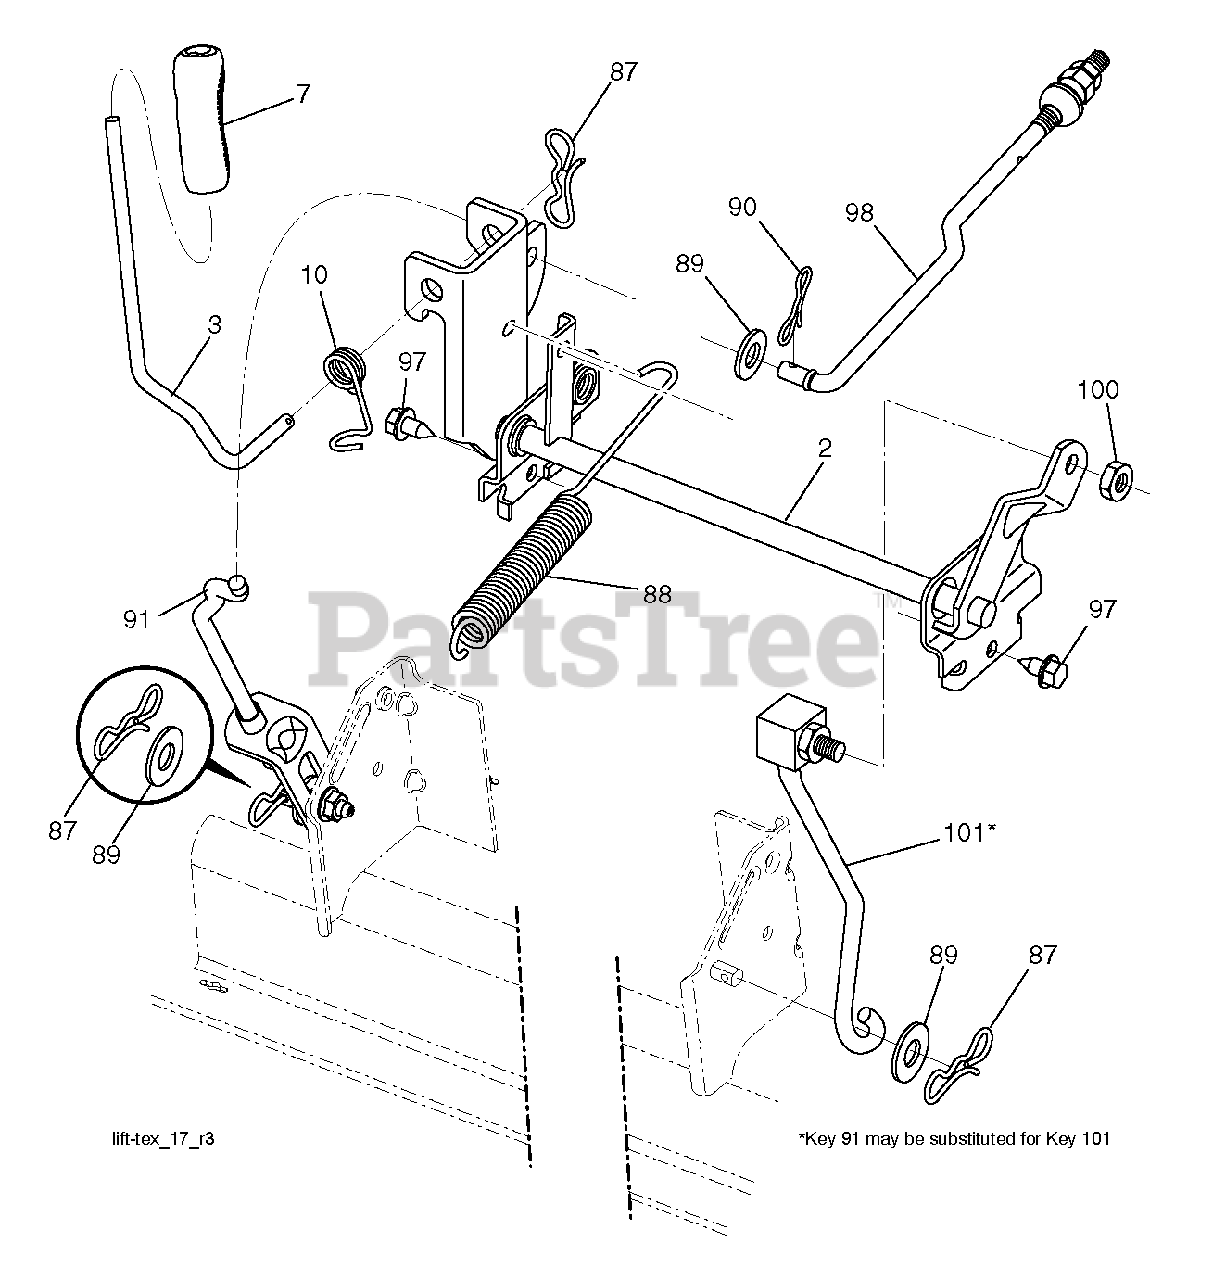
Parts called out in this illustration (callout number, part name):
2	SHAFT.ASM.CROSS.LIFT
3	LEVER.LIFT.HANDLE.LT
10	SPRING.TORSION.LIFT.HA
87	PIN.COTTER.7/16.BOW TI
88	SPRING.LIFT.ASSIST
90	PIN.COTTER.5/16.BOW TI
91	LINK.ASM.LIFT.REAR
97	SCREW, 3/8-16X3/4
98	LINK.ASM.SUSP.FRONT.MW
100	LINK.ASM.LIFT.FIXE.38/42/46"
